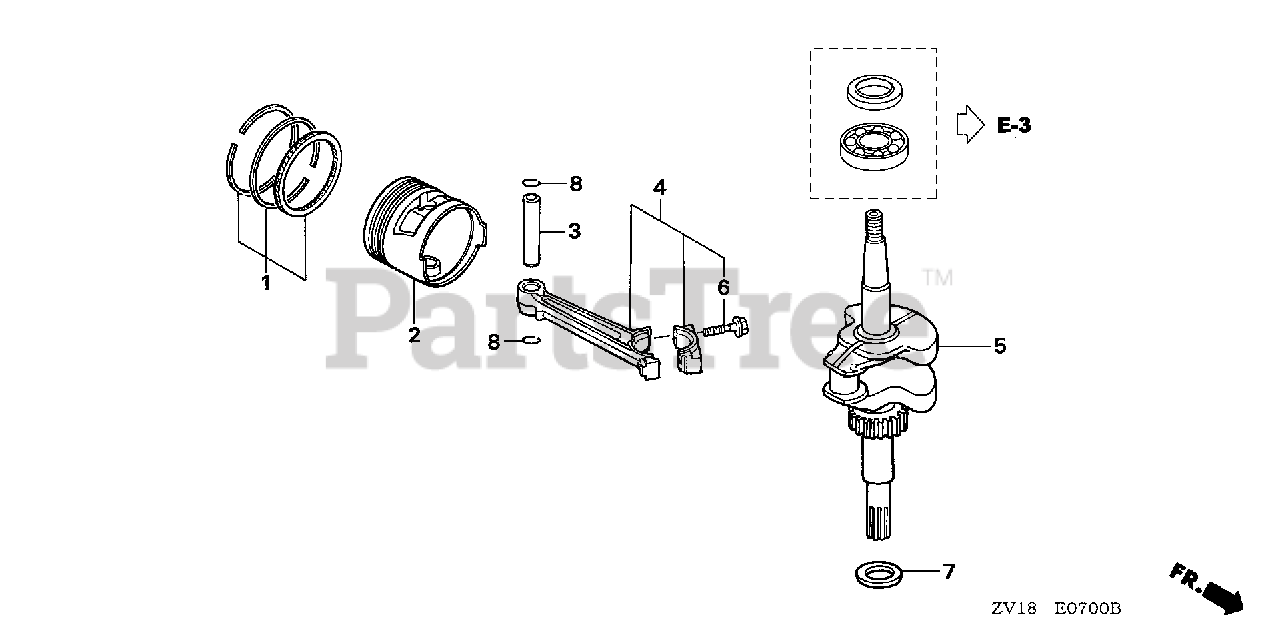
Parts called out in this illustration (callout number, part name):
1	RING SET, PISTON (STD) (TEIKOKU)
1	RING SET, PISTON (STD) (NIPPON)
1	RING SET, PISTON (0.25) (TEIKOKU)
1	RING SET, PISTON (0.75) (TEIKOKU)
3	PIN, PISTON
4	ROD ASSY., CONNECTING
5	CRANKSHAFT
6	BOLT, CONNECTING ROD
7	WASHER C, THRUST (25MM)
8	CLIP, PISTON PIN (18MM)
